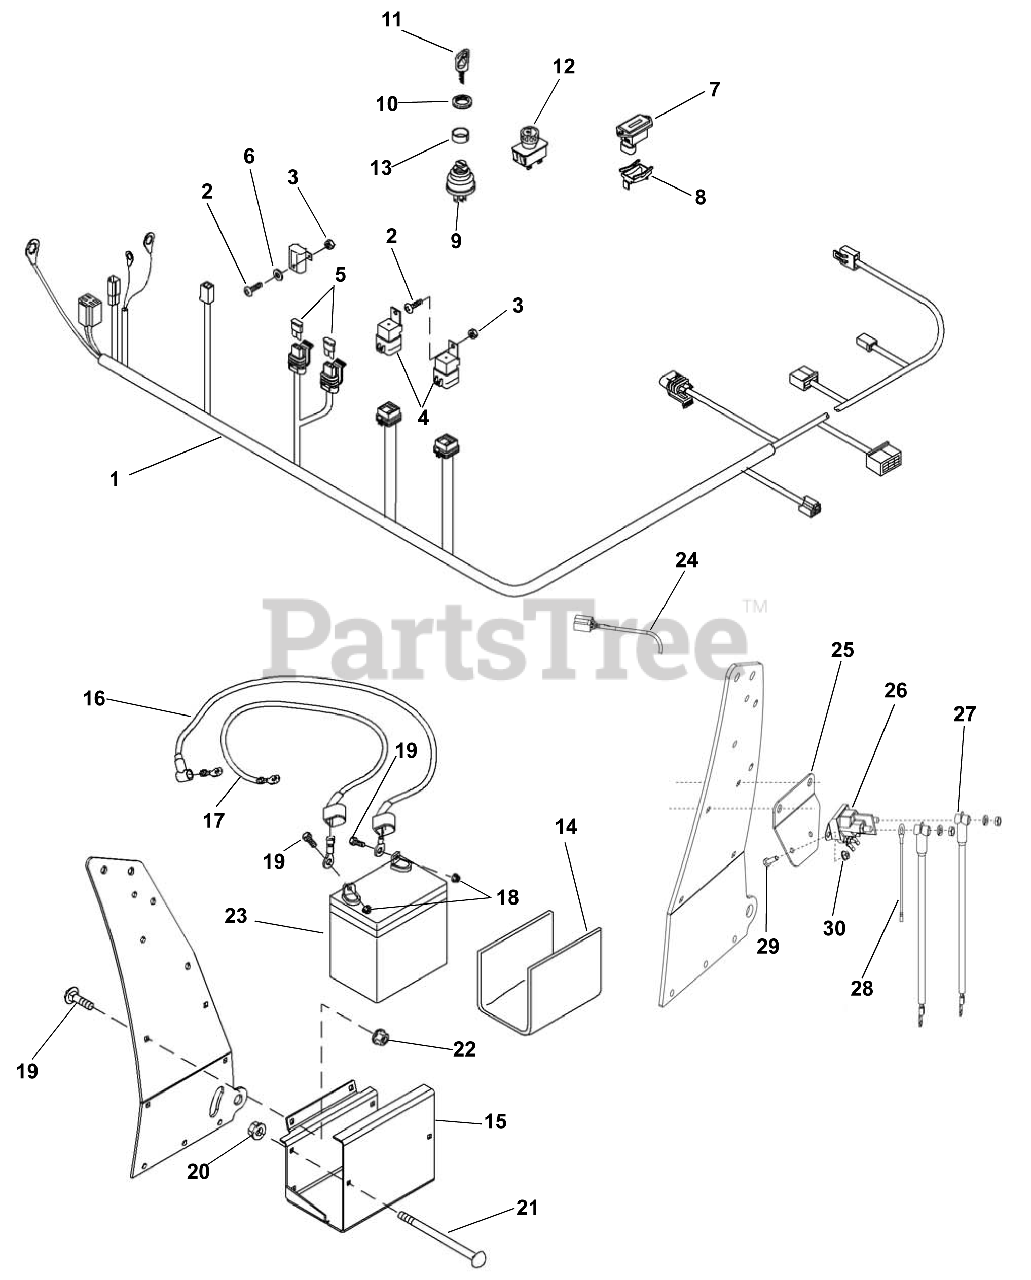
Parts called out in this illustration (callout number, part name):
1	WIRING HARNESS, MAIN
2	BLT-HEX M5-.8X16 YWZC
3	NUT-HEX M5X.8 PL
4	RELAY, SEALED W/BRACKET
5	FUSE, 20A
6	@WSHR-FL-STL.219X.50X.049 YWZC
7	METER, HOUR - LCD
9	KEY SWITCH
10	NUT, KNURLED
11	IGNITION KEY
12	SWITCH, PTO
14	ISOLATOR PAD, BATTERY
15	BATTERY BOX
16	CABLE, POSITIVE
17	CABLE, NEGATIVE
18	@NUT-LK-NYL M8-1.25 YWZC
19	BLT-RDHDSQNK M8-1.25X20 YWZC
20	@NUT-LK-NYL-FLG .31-18 YWZC
21	CAP SCREW, 5/16" X 6"
22	@NUT-LK-NYL M8-1.25 YWZC
23	Battery 12V U1-CCA 270 Min.
24	ADAPTER ASSY, KAWASAKI
25	SOLENOID MOUNTING PLATE
26	SOLENOID
27	STARTER CABLE
28	FUSIBLE LINK, 20A
29	@BLT-HEX .25-20X.75 GR5 YWZC
30	@NUT-SPNLK-FLG .25-20 YWZC
